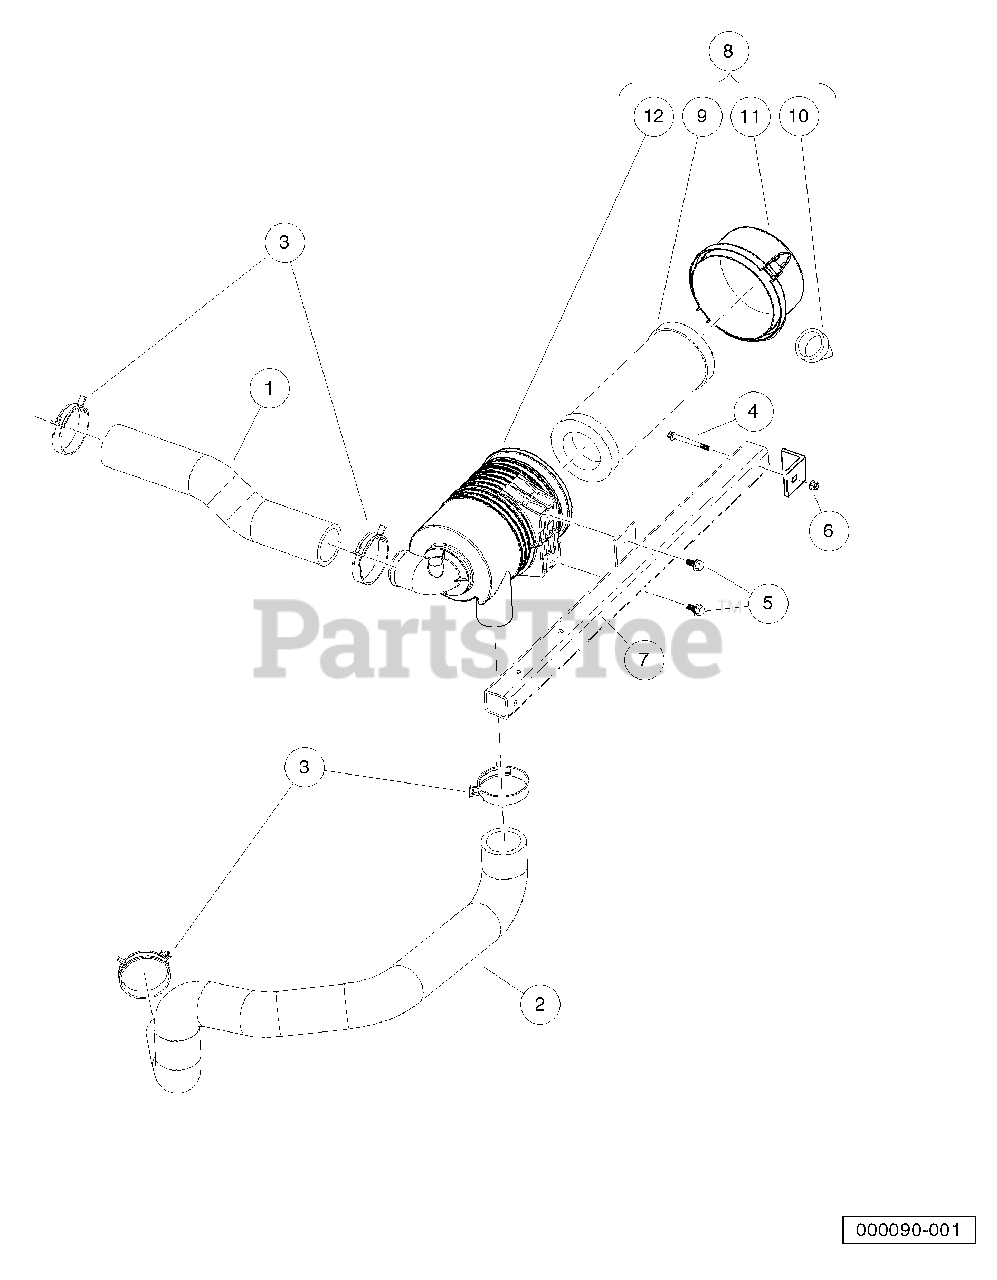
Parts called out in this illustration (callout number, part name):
1	Hose, Intake, GX620
2	Hose, Intake, Primary
3	Clamp, Hose, Ctb 64mm
4	Bolt, M 6 X 1.0 X 65 Hex, Flange, Head, Black
5	Bolt Flanged Head, M8 X1.25x 16 with Loctite
6	Nut Flg, M6 X 1.0 Nylon
7	Weldment, Support, Air Cleaner
8	Filter, Air, Canister, W/labe
9	Element, Filter, Air, 5 In
10	Valve, Evacuator, Filter Air
11	Cap, Latch Lock, Filter, Air
12	Body, Canister, Filter, Air
